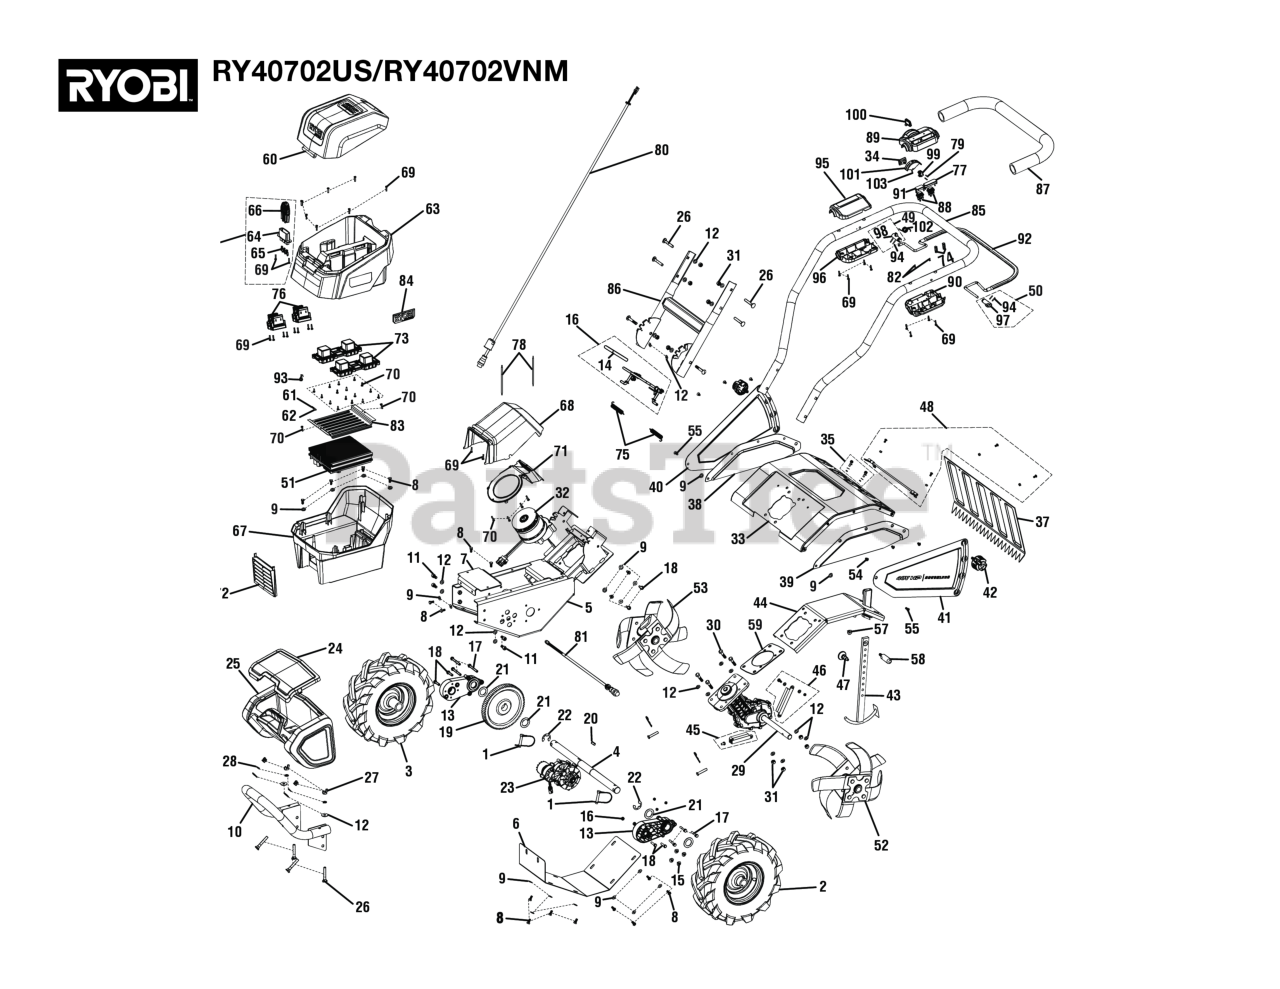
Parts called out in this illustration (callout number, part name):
1	Spring Pin
2	14 in. Pneumatic Tire (Left)
3	14 in. Pneumatic Tire (Right)
4	Tiller Wheel Shaft
5	Tiller Chassis Assembly
6	Tiller Skid Plate
7	Tiller Top Front Plate
8	Screw (M6 x 14 mm)
9	Washer (ID6.2 x OD15 x 0.08t)
11	Screw (M8 x 20 mm, Hex. Soc. Hd.)
12	Washer (ID8 x OD16 x 1t)
13	SP Output to Axle Housing w/Axle Bushing
14	Height Adjust Handle
15	Screw w/Washer (M4-18 x 10 mm, T20 Torx Pan Hd.)
16	Height Adjustment Assembly
17	Screw with Spring Washer (M6 x 35 mm)
18	Bolt (M6 x 25 mm, Hex Hd.)
19	Big Output Gear
21	Washer (OD1.031 x ID1.57 x 0.60t)
23	Gear Box Bushing Assembly
24	Sand Ballast Lid
25	Counterweight Housing
26	Carriage Bolt (M8 x 60 mm)
27	Wing Nut (M8 x 5.33 mm)
28	Spring Washer (OD14 x ID8.2 x 1.6t)
29	Gear Box Assembly
30	Screw (M8 x 35 mm, Hex Hd.)
31	Lock Nut (M8)
33	Upper Tine Housing
34	Dial Lever Insert
35	Tine Housing Hardware
36	Start Key Assembly
37	Rear Dirt Flap
38	Fender Side Tine
39	Lower Tine Housing (Left Side)
40	Left and Right Side Panels
41	Upper Tine Housing (Left Side)
43	Depth Adjustment Bracket Assembly
44	Rear Subframe
45	Lower Gear Box Support
46	Subframe Brace
47	Handle Lock Assembly
48	Hinge Shaft Assembly
49	Right Actuator Assembly
50	Left Actuator Assembly
51	Circuit Board Assembly
52	Tine Blade Assembly (Left)
53	Tine Blade Assembly (Right)
54	Screw (M6 x 10 mm, T25 Torx Hd.)
55	Screw (M6 x 16 mm, T25 Torx Hd.)
56	Screw (M8 x 30 mm, Hex Hd.)
57	Flange Nut (M8)
58	Drag Stake Handle
59	Rubber Plug for Gear Box
60	Battery Cover
61	Compression Spring
62	Battery Door Axle
63	Battery Bucket
64	Key Connector Base
65	Female Terminal
66	Key Connector Base Assembly
67	Battery Base
68	Tiller Motor Cover
69	Screw (M4 x 18 mm, T20 Torx Pan Hd. S.T.)
70	Screw (M4.2 x 12 mm, T20 Torx Pan Hd.)
71	Turbine Cover
72	Vent Area
73	Battery Ejector Assembly
74	Compression Spring
75	Custom Spring
76	Battery Contact Holder Assembly
77	Button Cover
79	Pin for Switch
81	Wire Keep With Machine
82	SCREW, CH M3 PH B\L=6MM
83	Cooling Cover
84	RYOBI Logo Badge
85	Upper Handle Tube Assembly
86	Lower Handle Tubes
87	Handle Grip
88	Center Switch
89	Left Control Pod (Top)
90	Left Control Pod (Bottom)
91	Switch Button Cover
92	Start Trigger
93	Battery Door Torsion Spring
94	Spring Pin
95	Right Control Pod Top (Top)
96	Right Control Pod (Bottom)
97	Left Actuator
98	Right Actuator
99	Micro Switch
100	Speed Control Paddle (Top)
101	Speed Control Paddle (Bottom)
102	Torsion Spring
103	Screw (M x 12 mm, Pan Hd.)
